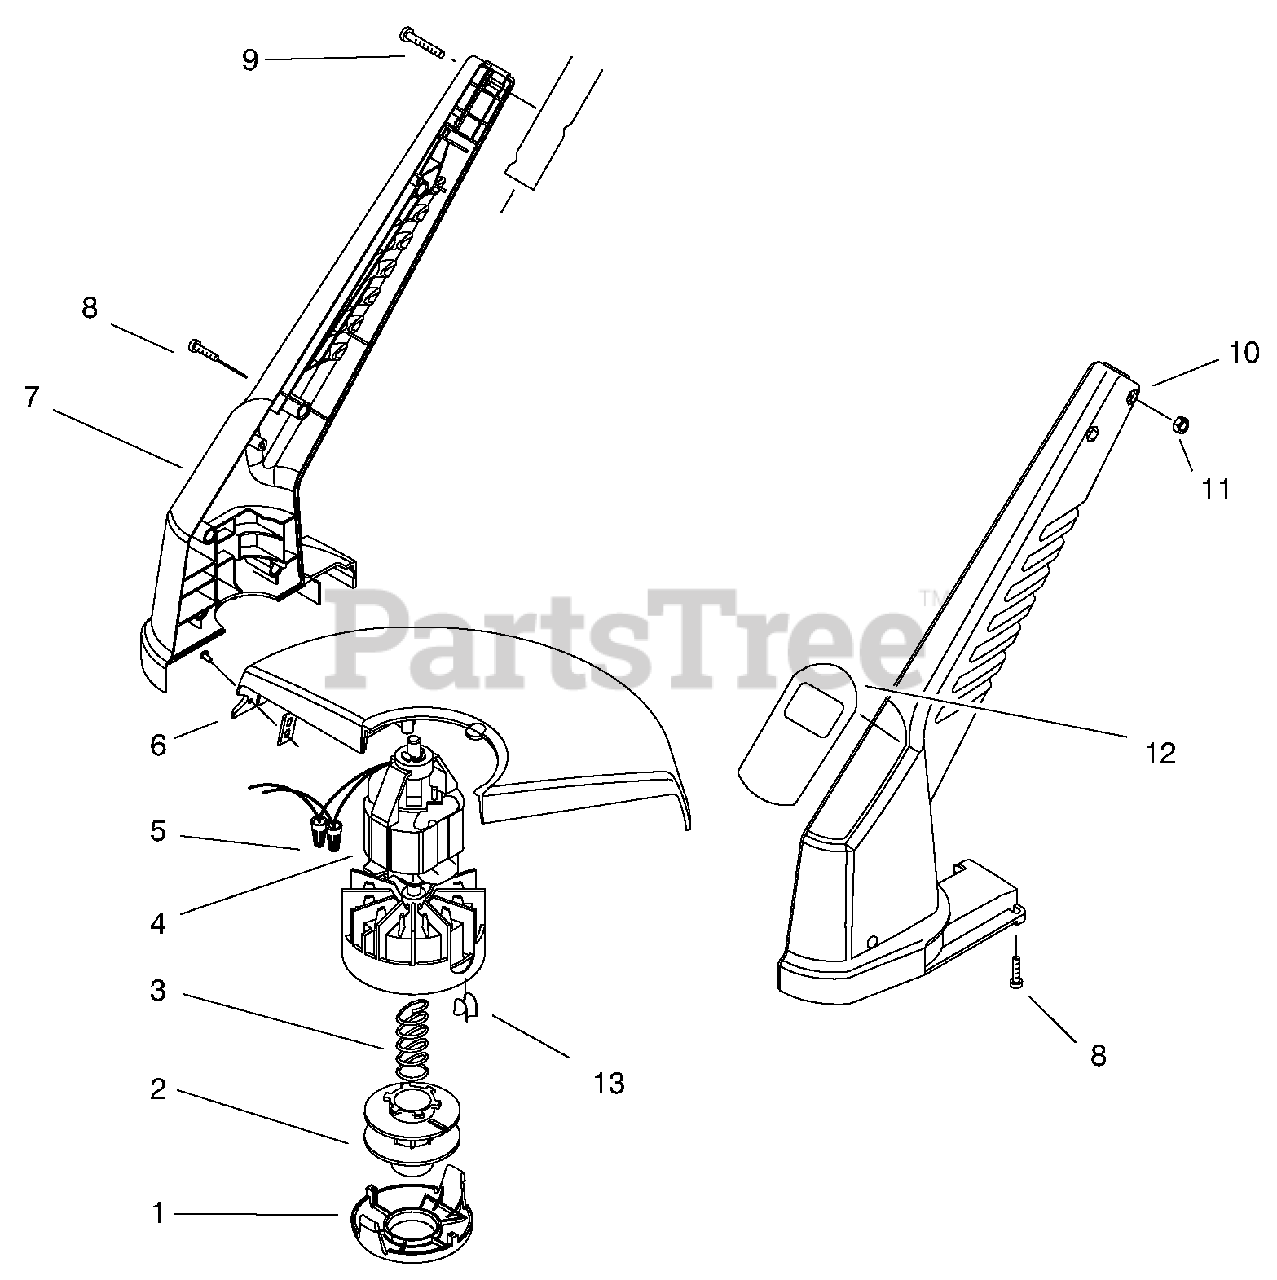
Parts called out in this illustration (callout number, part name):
4	Motor Assembly (Incl. Ref. #13)
5	Connector-Wire Nut
6	Shield-14"
7	Housing R.H.
9	Screw-Pan Hd.
10	Housing L.H.
12	Decal-14" Trimmer
